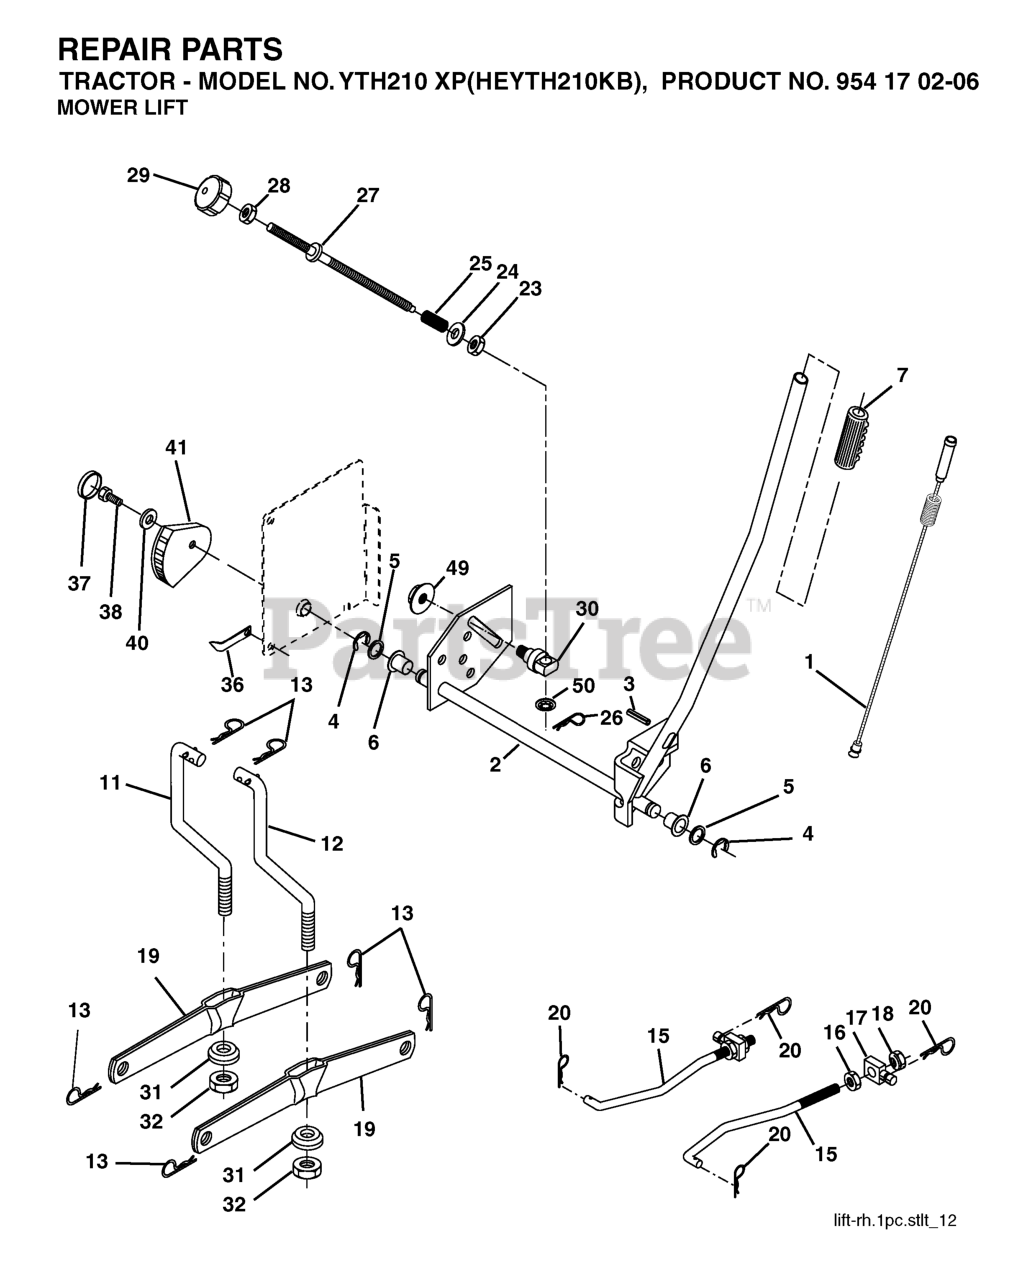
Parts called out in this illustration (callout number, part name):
1	WIRE ASM INNER W/ PLUNGER LT
2	SHAFT ASM R HANDLE
3	PIN GROOVE.
4	RETAINING RING LT
6	BEARING.NYLON
7	GRIP HANDLE
8	PLUNGER BUT KIT
11	LINK LIFT LH
12	LINK LIFT RH
13	RETAINER-SPRNG RB
15	LINK.SUSPENSION.FRONT
16	NUT.HEX.JAM.1/2-13
18	NUT.LK.W/WSH.1/2.
19	ARM.REAR.SUSPENSION
20	SPRING RETAINER
25	SPRING**
26	RETAINER CLIP
27	ROD ADJ LIFT
28	NUT
29	KNOB INF 3/8-16
31	BEARING.PIVOT.LIFT
32	NUT CROWNLOCK 3/8-24
36	POINTER, HEIGHT INDICATOR(2 2)
38	SCREW 5/16-18X1
41	IND. HEIGHT STLT
49	NUT
50	NUT PUSH M
